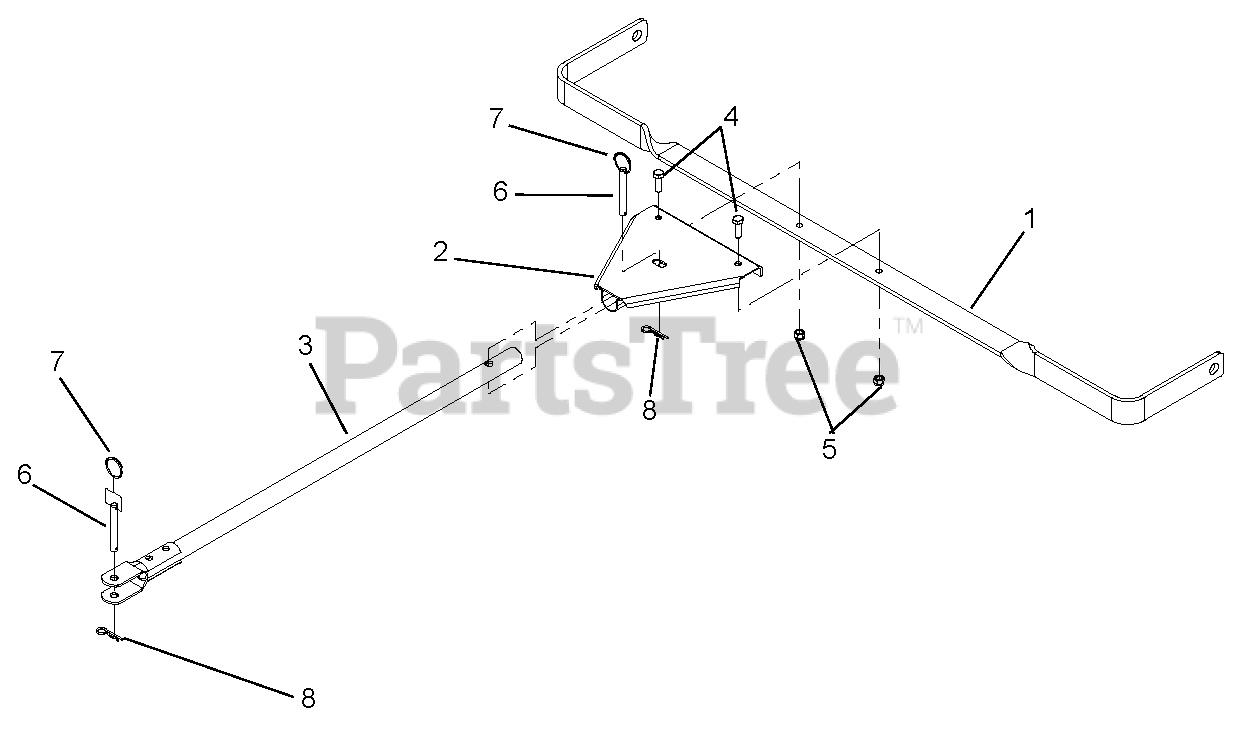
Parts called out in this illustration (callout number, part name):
4	2
5	2
8	2
